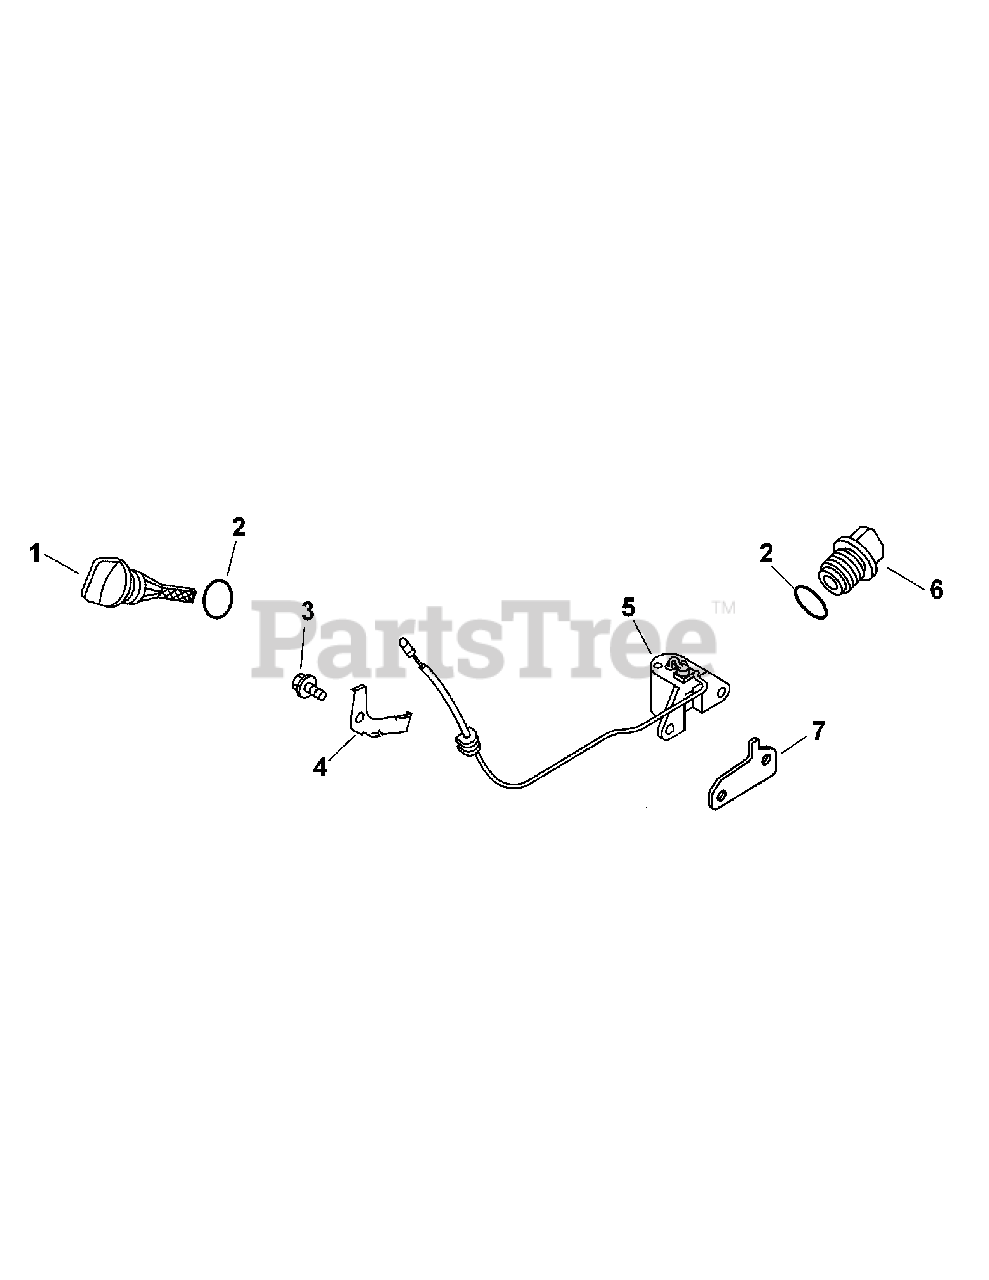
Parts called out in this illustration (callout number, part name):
1	Plug, Oil Level
5	Switch, Oil Level
7	Spacer / Oil Level Guage
